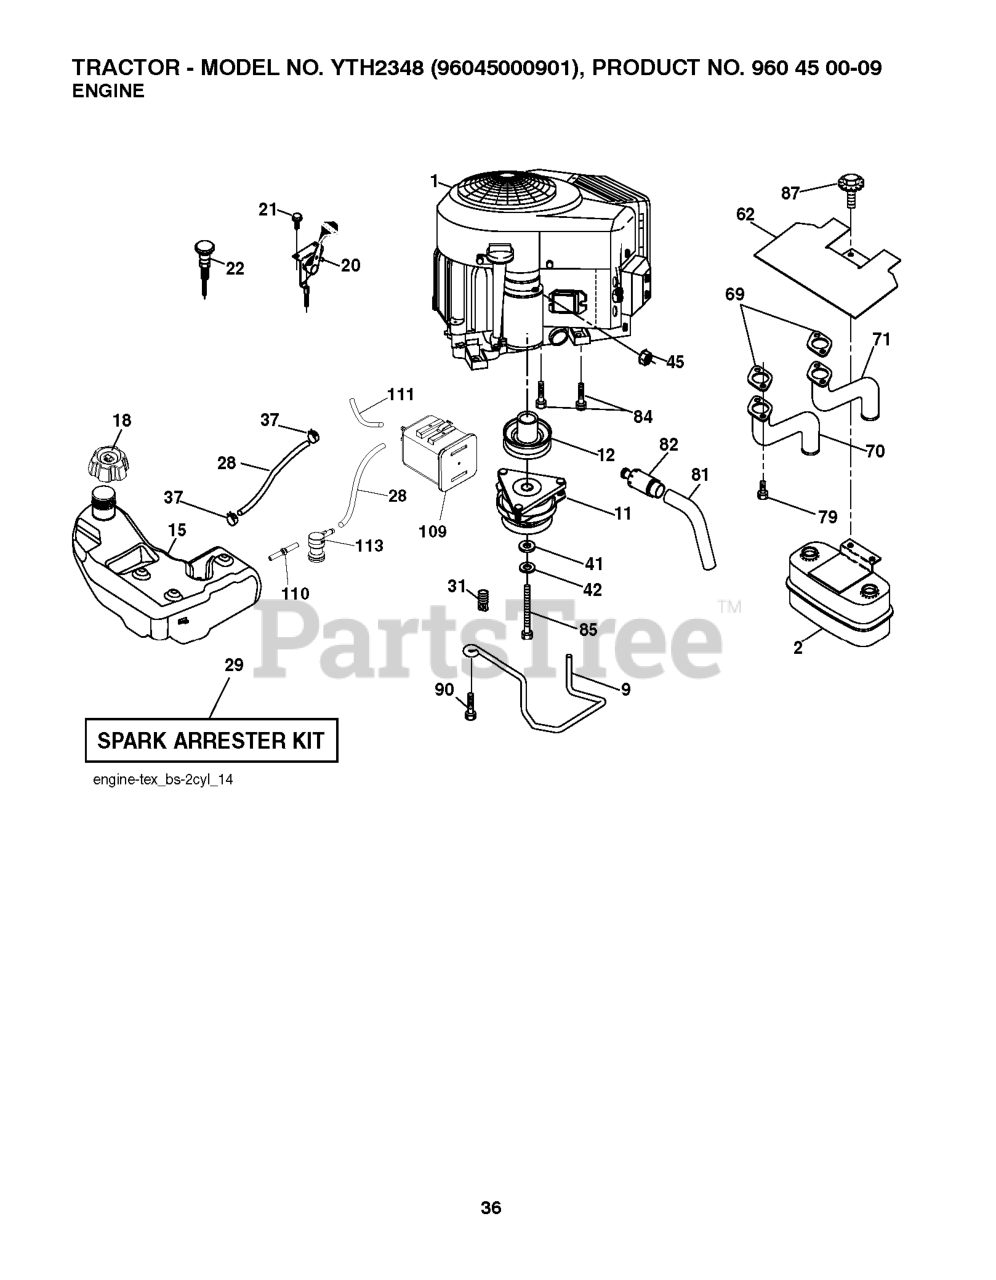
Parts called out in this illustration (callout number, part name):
2	MUFFLER.TWIN.CYL.LOW.TONE
9	KEEPER.BELT.ENGINE.4.2
11	CLUTCH.ELECTRIC.LT.48"*
12	PULLEY.ENGINE.TUFFTORQ
15	TANK.ASM.FUEL.3GA.CARB
18	CAP ASM
20	THROTTLE CABLE
21	SCREW.#10 X 0.750.BOS
22	CONTROL.CHOKE.ERGO.PUSH-IN.BLA
28	LINE.FUEL.64"REAR.EMIS
29	KIT.SPARK ARRESTOR 794945 B&S
37	HOSE CLAMP
42	LOCKWASHER
45	NUT
62	RP SHIELD HEAT MUFFLER
69	GASKET.MUFFLER
70	RP.EXHAUST.TUBE.LH.BS/TWIN
71	EXHAUST.TUBE.RH.BS/TWIN
79	SCREW.SOCKET.HEAD.5/16-18
81	TUBE, DRAIN OIL ASM.
82	PLUG DRAIN OIL EASY
84	SCREW.3/8-16
85	BOLT HEX 7/16-20X4-1/4"
87	BOLT.5/16-18UNCX3/4 W/SEMS.BLK
90	SCREW 3/8-16X1
109	CANNISTER, CARBON
110	VALVE.ASM.ANTI-SLOSH
111	RP PURGE LINE
113	VALVE.SLANT.CARTRDG.90 DEG.TEX
